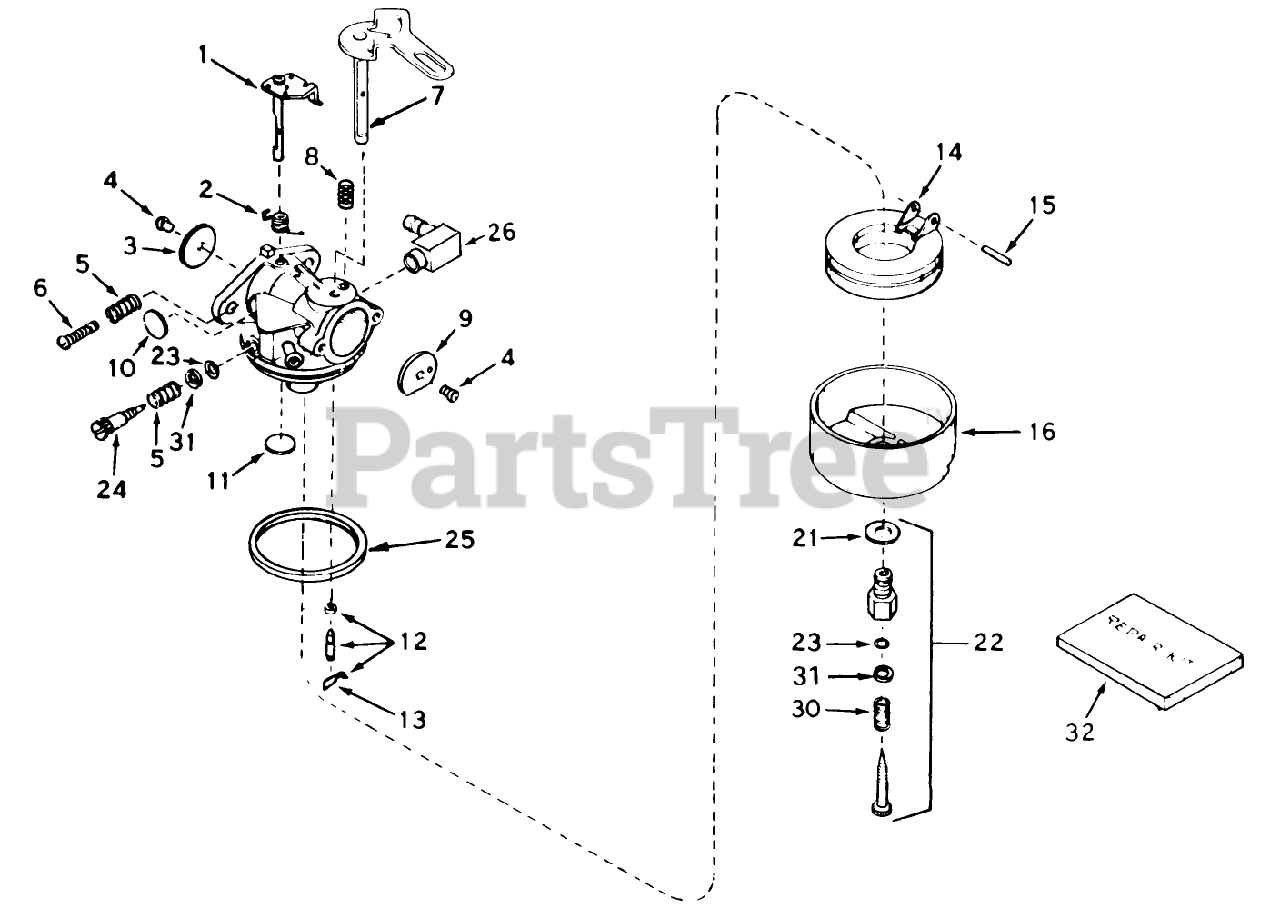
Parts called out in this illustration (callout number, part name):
1	Throttle Shaft and Lever ASM
2	Spring, Return
3	Shutter-Throttle
4	Screw-Shutter
5	Spring-Tension
6	Screw-Throttle Crack Screw / Idle Speed
7	Choke Shaft and Lever Asm
8	Spring-Positioning, Choke
9	Shutter-choke
10	Plug-Welch, Idle Mixture Well
11	Plug-Welch, Atmospheric Vent
12	Inlet Needle, Seat Clip Assy. (Incl. No. 13)
13	Clip-Spring
14	Float
15	Shaft-Float
16	Bowl-Float (no drain)
21	Washer-Bowl Nut
22	Adjustment Screw Assy., Main (Incl. Nos. 5A, 21 23)
23	ORing
24	Screw, Idle Adj.
25	O Ring-Bowl, Float
26	Fitting-Fuel
30	Spring
31	Washer
32	Repair Kit (Incl. items marked *)
